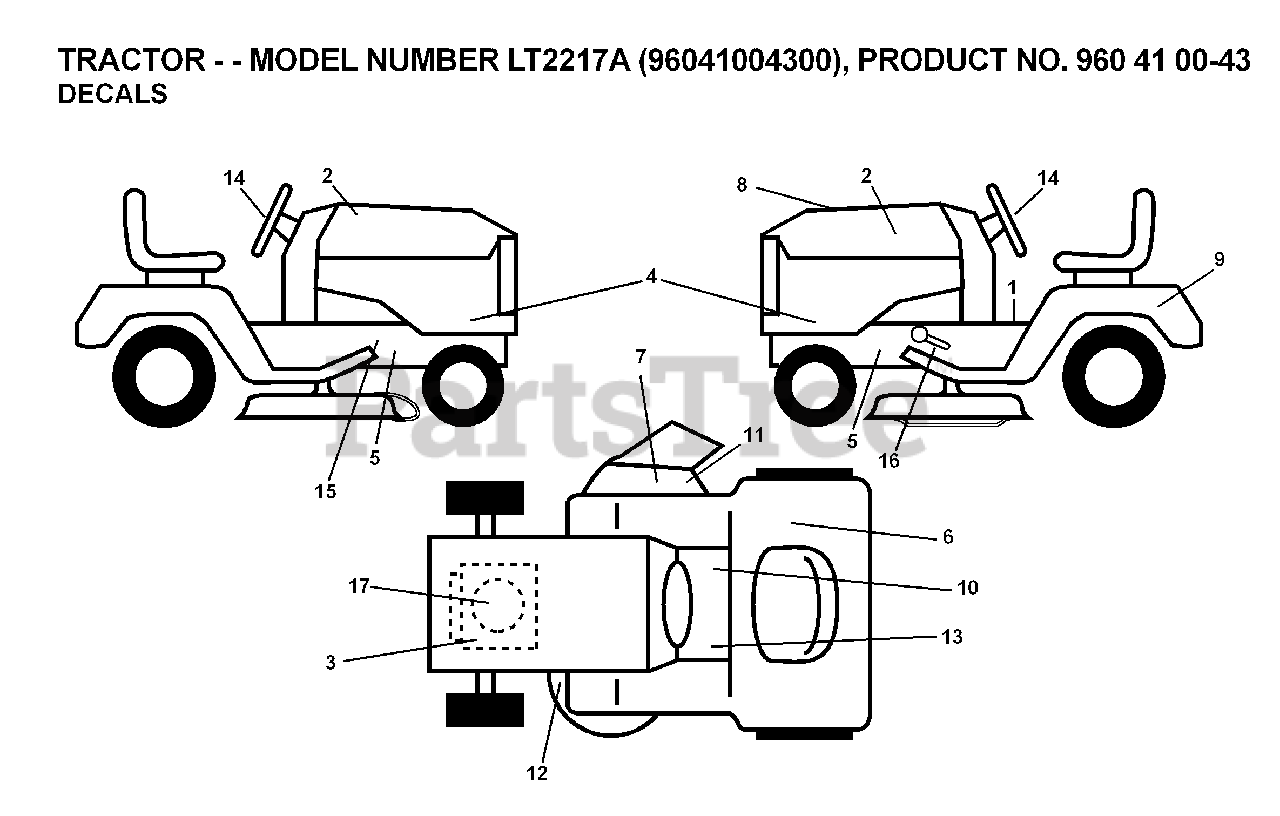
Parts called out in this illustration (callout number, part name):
7	DECAL.INTERNATIONL.CUTFINGER
9	DECAL BTRY SYMBOLS
10	DECAL PARK BRAKE
11	DECAL, DEFLECT WARNING
12	DECAL V BELT SCHEMATIC
